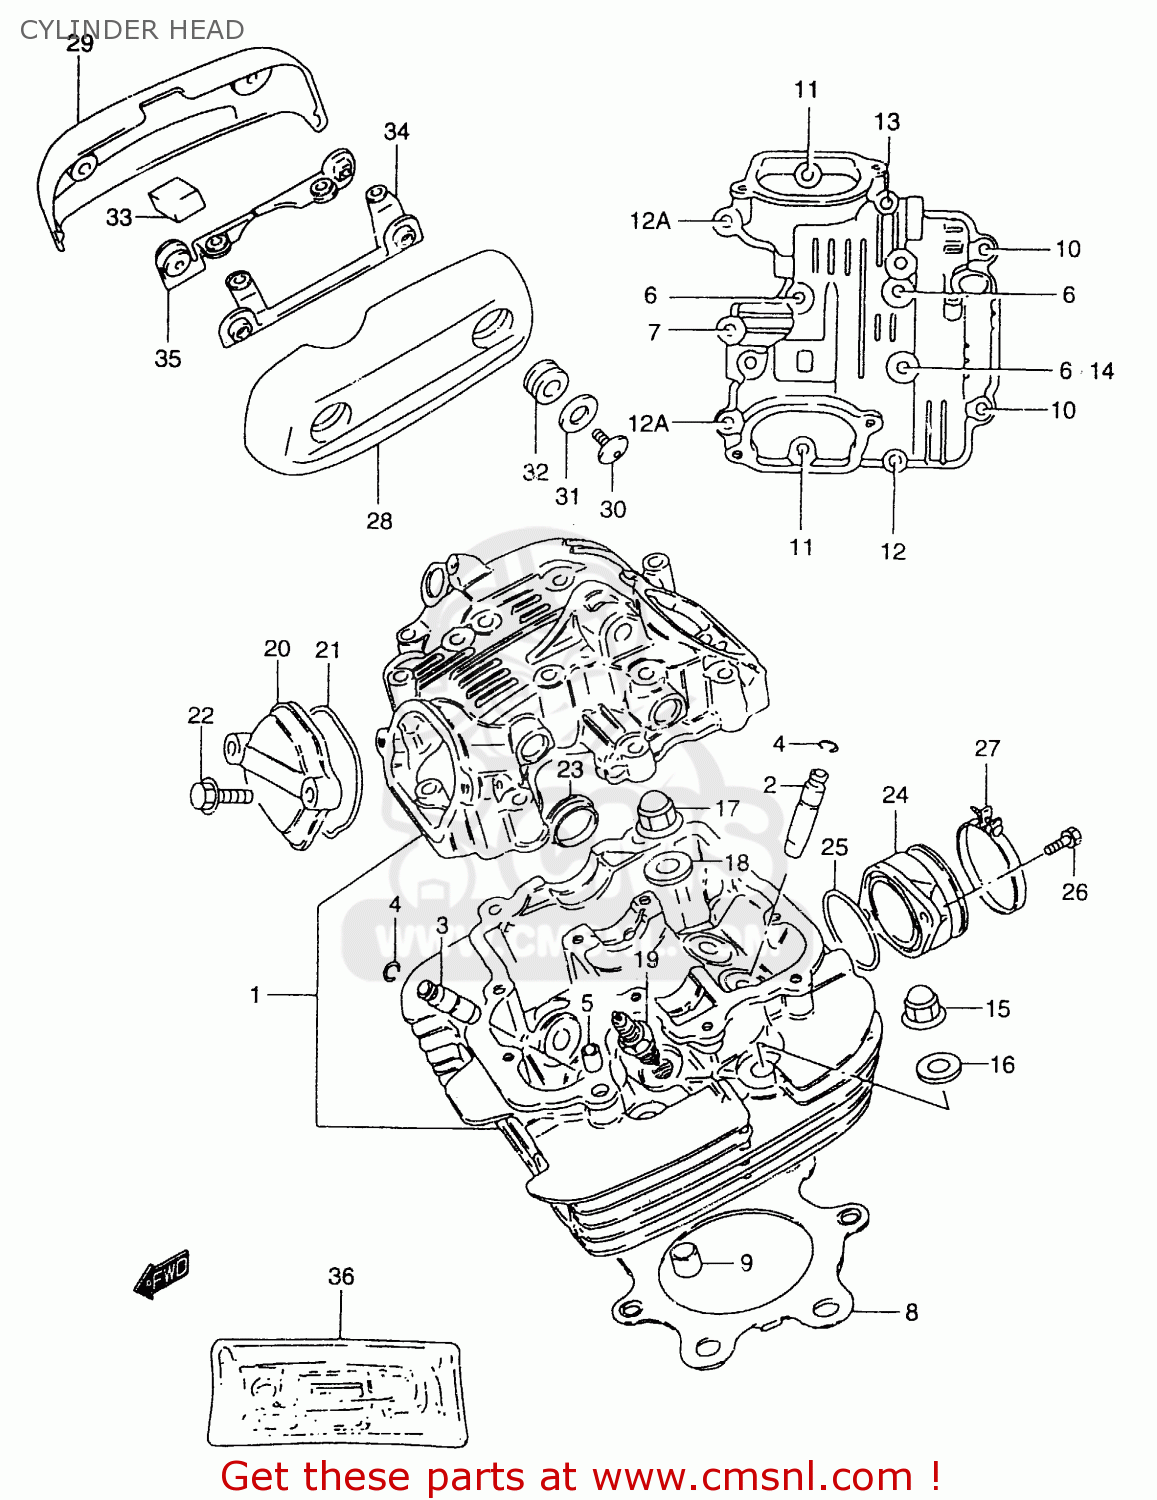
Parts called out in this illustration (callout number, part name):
1	HEAD ASSEMBLY,CYLINDER
2	GUIDE,INTAKE VALVE
3	GUIDE,VALVE
4	RING,SNAP
5	PIN(6.2X8X11)
6	BOLT
7	BOLT
8	GASKET,CYLINDER HEAD (NAS)
9	PIN
10	BOLT(6X120)
11	BOLT
12	BOLT
12A	BOLT
13	BOLT
14	GASKET(5.8X13X1.2) (NAS)
15	NUT
16	WASHER (10.5X22X2.3)
17	NUT
18	GASKET(10.5X22X2) (NAS)
19	PLUG,SPARK(DR8EA)
20	CAP,INSPECTION
21	O RING(D:2.4,ID:23)
22	BOLT
23	PLUG(OD:30)
24	PIPE,INTAKE
25	O RING(D:2.4,ID:39.7)
26	SCREW ,6X16
27	CLAMP
28	CAP,CYLINDER HEAD COVER,L
29	CAP,CYLINDER HEAD COVER,R
30	BOLT
31	WASHER(6.5X24X1.6)
32	CUSHION
33	DAMPER,HEAD CAP,R
34	BRACKET COMP,HEAD CAP
35	BRACKET COMP,HEAD CAP
36	GASKET SET (NAS)
